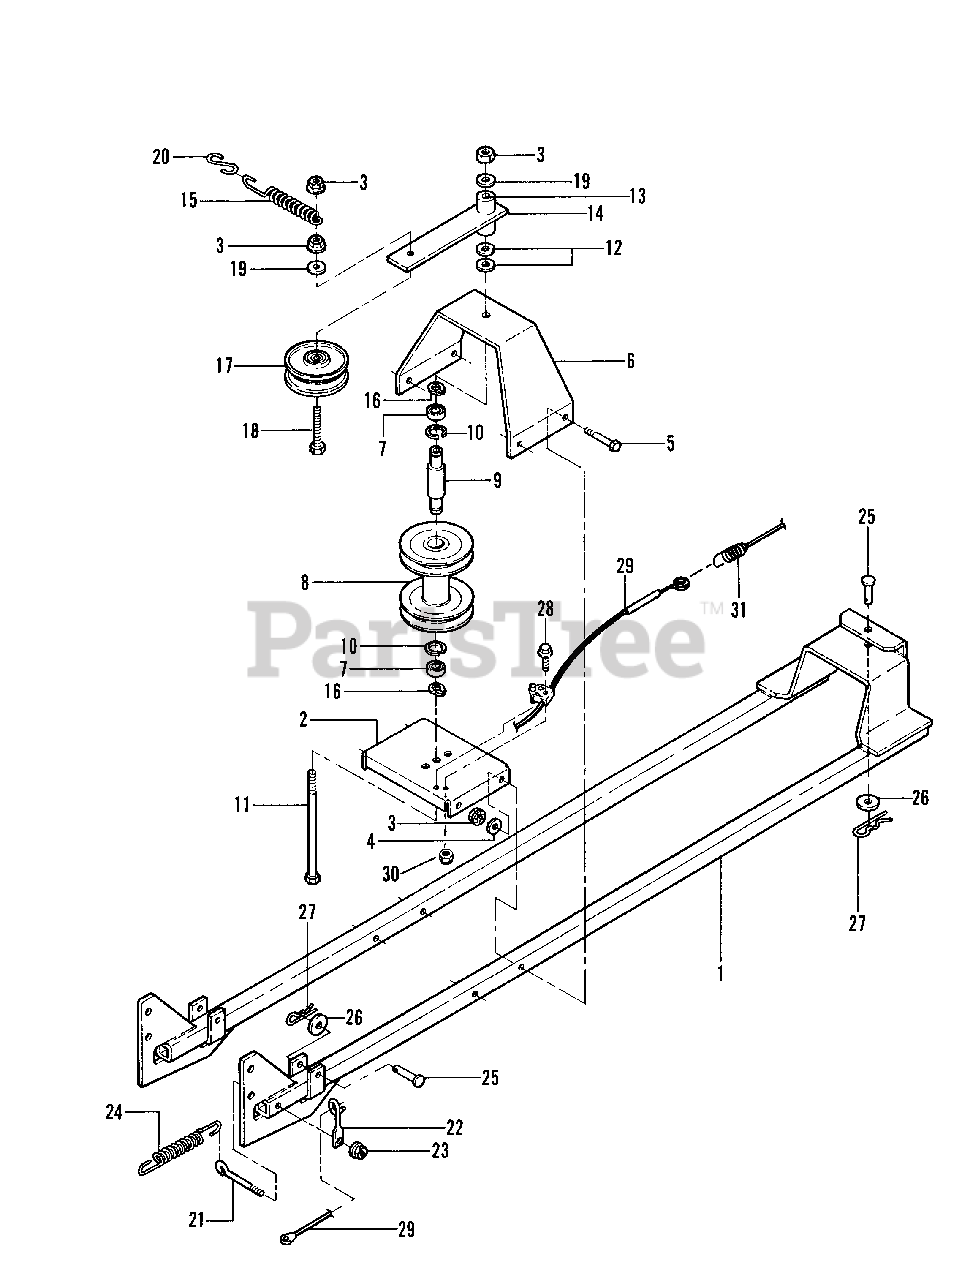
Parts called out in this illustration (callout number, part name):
1	SUPPORT, Tube Structure
2	SUPPORT, Lower Idler
3	NUT, 3/8-16 Hex Lock
4	WASHER, 3/8" Flat
5	SCREW, 3/8-16 x 2" Hex Head Cap
6	SUPPORT, Upper Idler
7	BEARING, Spindel
8	IDLER, Stacked
9	SHAFT, Stacked
10	RING, Internal Jack Shaft
11	BOLT, 3/8-16 x 6" Hex Head Cap, Grade 5
12	WASHER, 3/8" Flat
13	SPACER
14	ARM, Idler
15	SPRING, Idler
16	RING, Bearing Retaining
17	PULLEY, Idler
18	SCREW, 3/8-16 x 2 1/4" Hex Head Cap, Y.Z.C., Grade 5
19	WASHER, 3/8 Split Lock
20	S-HOOK
21	BOLT, Eye
22	GUIDE, Pull Rope
23	NUT, 1/4-20 Hex Center Lock
24	SPRING
25	PIN, Clevis
26	WASHER, Flat, 17/32" I.D. x 1 1/16" O.D.
27	PIN, Hair
28	SCREW, #10-32 x 5/8" Hex Washer Head, Grade 5
29	ASSEMBLY, Cable
30	NUT, #10-32 Hex Nyloc
31	CABLE, PTO
